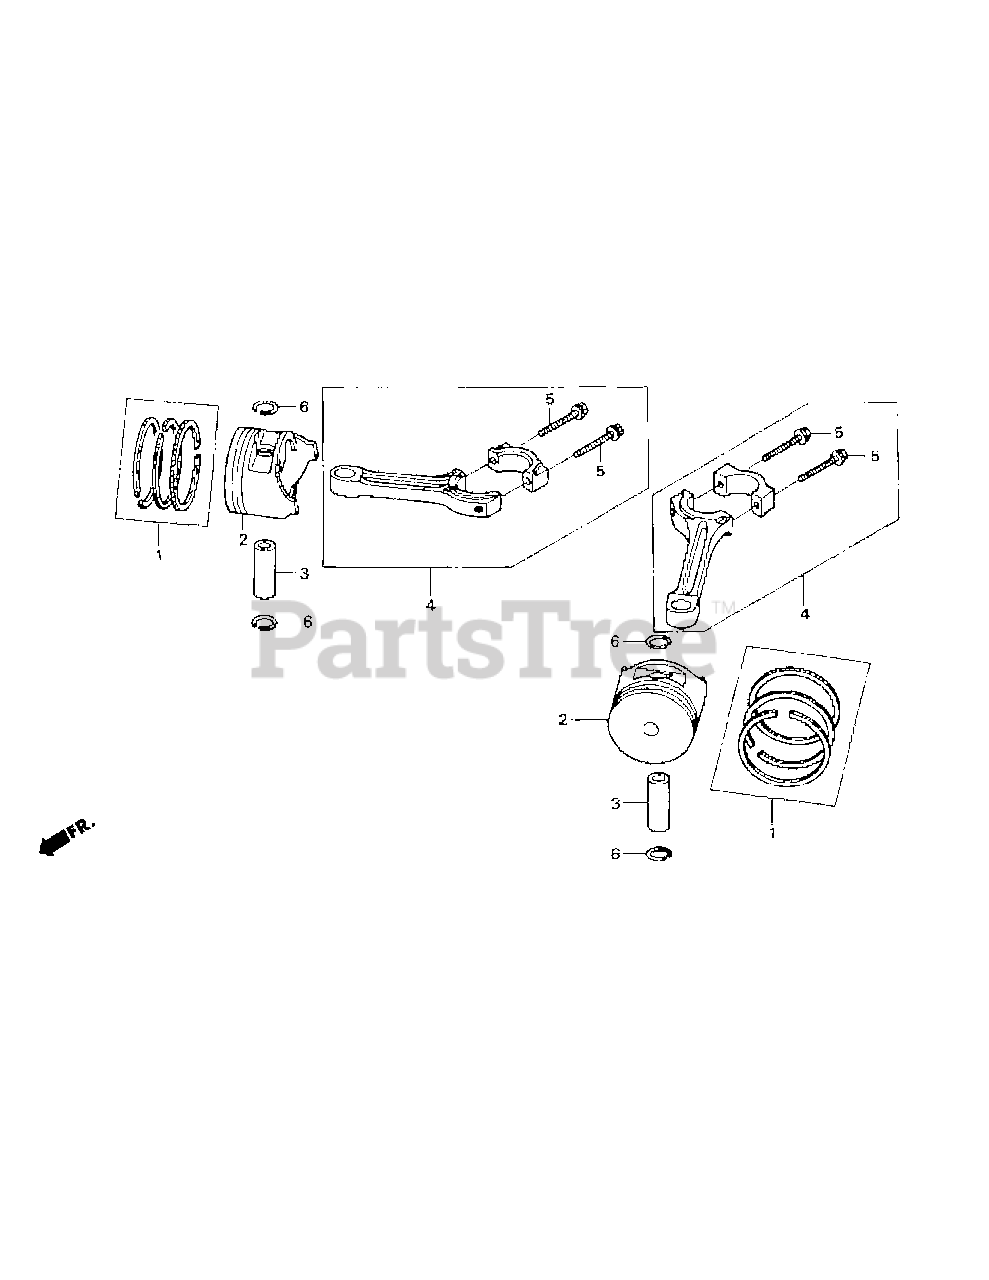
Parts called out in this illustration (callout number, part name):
1	Piston Ring Set (Std.)
1	Piston Ring Set (OS .25)
1	Piston Ring Set (OS .50)
1	Piston Ring Set (OS .75)
2	Piston (Std.)
2	Piston (OS .25)
2	Piston (OS .50)
2	Piston (OS .75)
3	Piston Pin
4	Connecting Rod Assy.
6	Connecting Rod Bolt (6x37)
7	Piston Pin Clip
